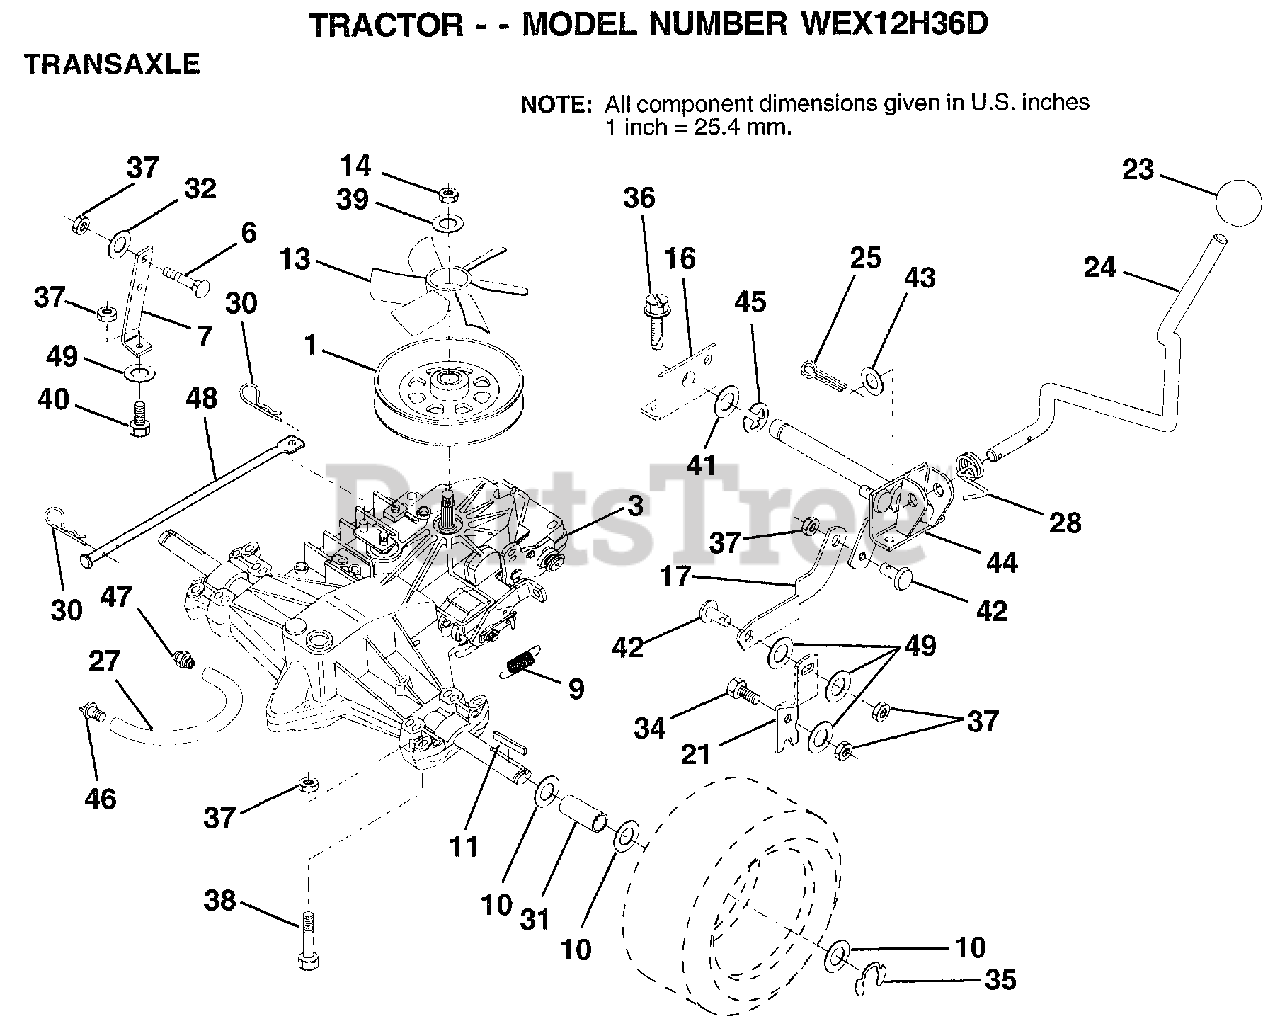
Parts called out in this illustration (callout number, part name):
1	PULLEY.V-GROOVE
6	BOLT
7	STRAP.TORQUE.HYD
9	SPRING.BRAKE.RETU
10	WASHER
11	SQUARE KEY
13	FAN.HYDRO.6FANS
14	"LOCKNUT,1/2-20UNF"
16	SUPPORT.HDLE.SHFT
17	LINK.SHIFT.HYD.LR
21	LEVER.SHIFT.TRANS
23	KNOB T (1/2-HOLE)
24	ROD.SHIFTER.HYD.
25	PIN COTTER 1/8
27	"LINE FUEL HYD 4"""
28	SPRING.TORSION.LR
30	RETAINER M
31	SPACER SPLIT
32	WASHER
35	E-RING LT
36	SCREW
37	NUT
38	BOLT.HEX.FLGHD
39	WASHER
40	BOLT.HEX.5/16-1.5
41	WASHER
42	PIN.PIVOT.SHIFT.
43	WASHER
44	SHAFT.PIVOT.LR.
48	ACTUATOR.BYPASS
49	WASHER M
